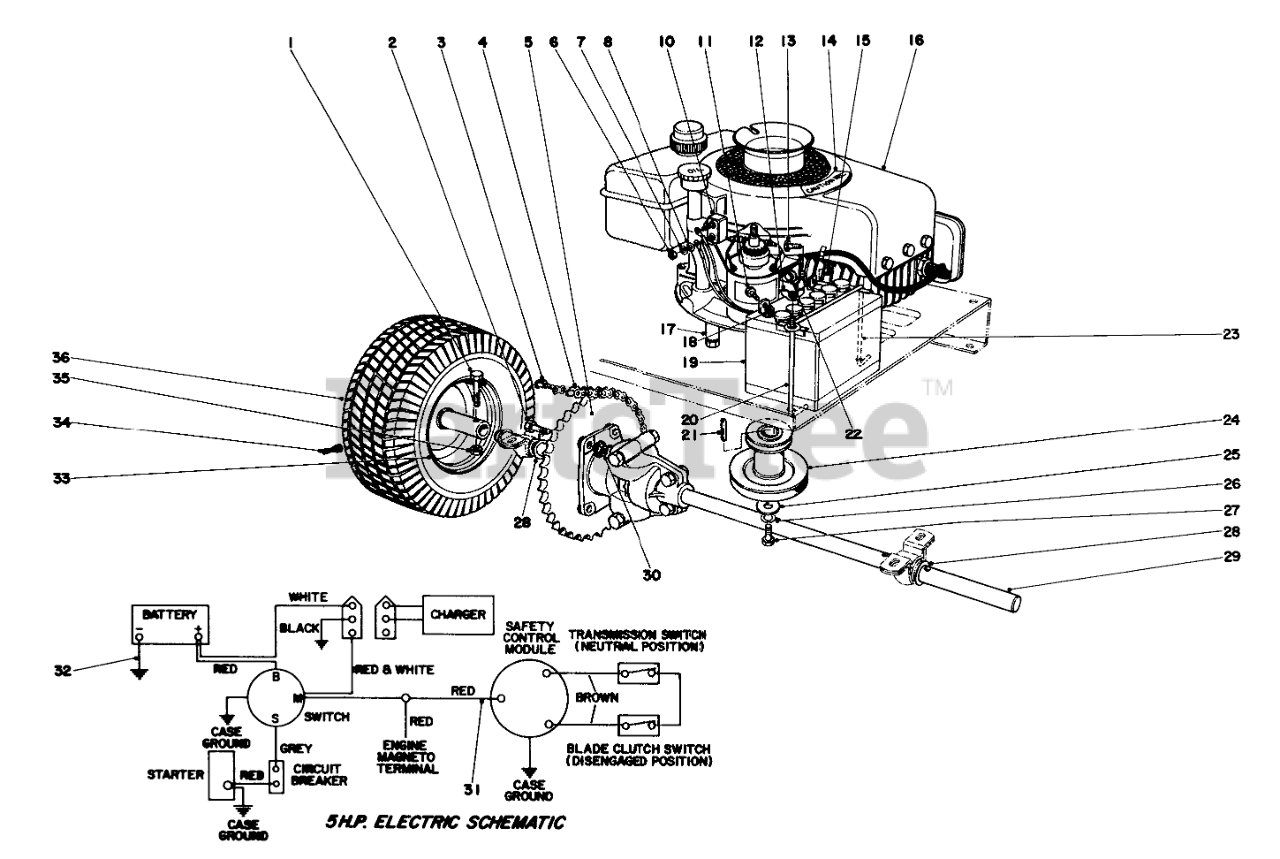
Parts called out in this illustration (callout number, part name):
1	SCREW-HH
2	SCREW-HH
3	LINK-CONNECTING
4	Roller Chain
5	Sprocket
6	NUT-HEX
7	WASHER-LOCK/SP
8	WASHER-FLAT
10	Breaker Circuit
11	SCREW-HH
12	NUT-WING SPECL
13	SCREW-HH
14	Decal
15	NUT-HEX
16	Engine
17	Extension Oil Drain
18	NUT-HEX
19	Battery
20	ROD-SUPPORT, BATTERY
22	SCREW
23	Battery Clamp
24	Pulley
25	Washer
26	WASHER-LOCK
27	SCREW-HH
28	WASHER
29	Differential
30	NUT-LOCK, CONE
31	Wiring Harness
32	ENG-GROUND WIRE ASM
34	STEM-VALVE
35	NUT-LOCK, CONE
36	Tire
